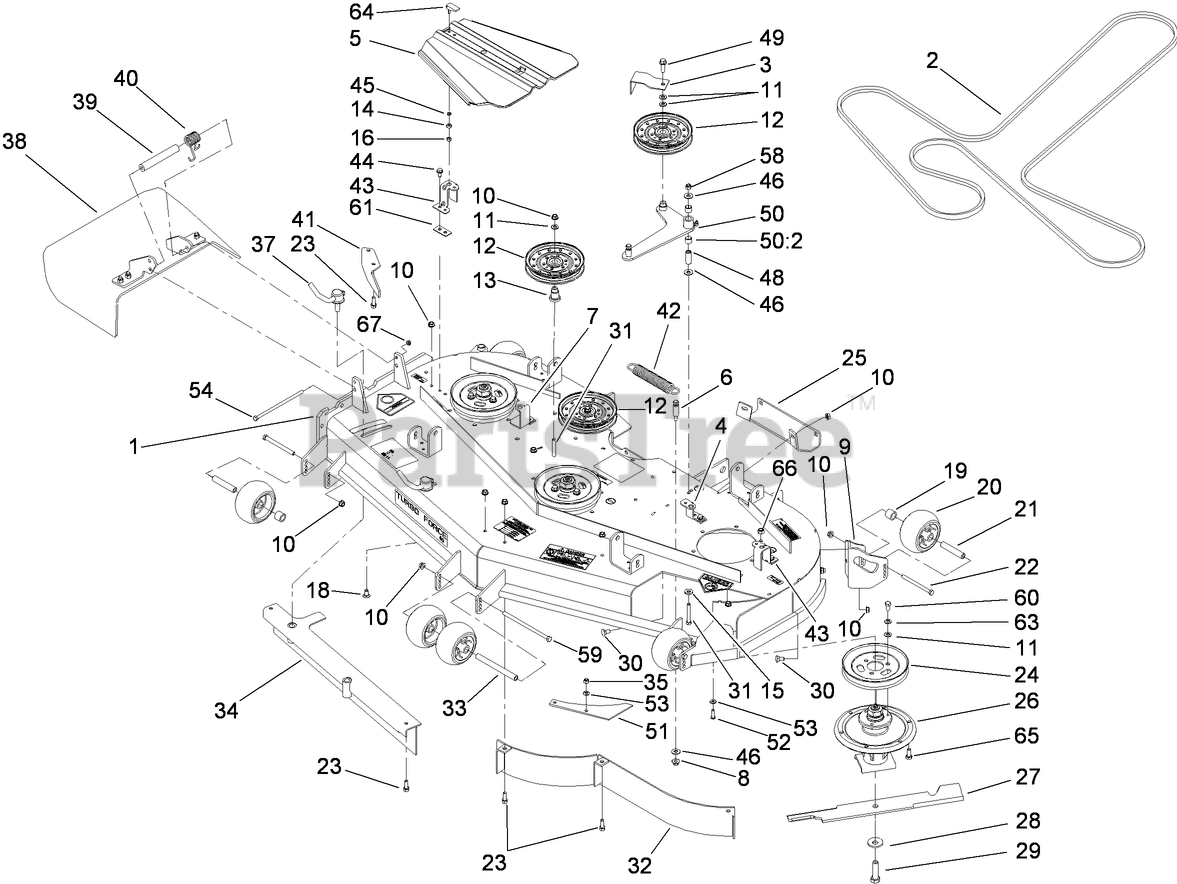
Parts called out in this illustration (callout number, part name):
1	DECK DECAL ASM
2	BELT-V
3	GUIDE-BELT
4	BRACKET-COVER, TALL
5	COVER-BELT
6	PIN-THREADED, SPRING ANCHOR
7	BRACKET-COVER
8	NUT-HF
9	MOUNT-WHEEL, LH
10	NUT-HHF, WHIZ
11	WASHER-FLAT
12	Idler-Flat
13	MOUNT-PULLEY
14	BUSHING-LATCH, SWELL
15	WASHER-BELLEVILLE
16	NUT-LOCK, HH
18	SCREW-CARR
19	TUBE-SPACER
20	ROLLER-SCALP, ANTI
21	TUBE-SPANNER
22	SCREW-HH
23	SCREW-HWH
24	Pulley
25	Plate-Skid
26	SPINDLE ASM
27	BLADE-HI FLOW
28	Washer-Blade Bolt, Heavy
29	SCREW-BLADE
30	SCREW-CARR
31	SCREW-HH
33	SPACER-WHEEL
35	NUT-LOCK, NI
37	LEVER ASM
38	RUBBER DEFLECTOR ASM
39	SPACER
40	SPRING-TORSION
41	BAFFLE-DISCHARGE
42	SPRING-EXTENSION
43	BRACKET-COVER
44	SCREW-HWHTF
45	WASHER
46	WASHER-FLAT
48	BUSHING
49	SCREW-HHF
50	DECK IDLER ARM ASM
50:2	SLEEVE-BEARING
51	PLATE-TURBO
52	SCREW-HSBH
53	WASHER-SPRING
54	SCREW-HH
58	NUT-LOCK, NI
59	SCREW-HH
60	SCREW-HH
61	SPACER-COVER, BELT
63	WASHER-BELLEVILLE
64	HANDLE-LATCH, SWELL
65	SCREW-HH
66	NUT-LOCK, NI
67	NUT-LOCK, NI
